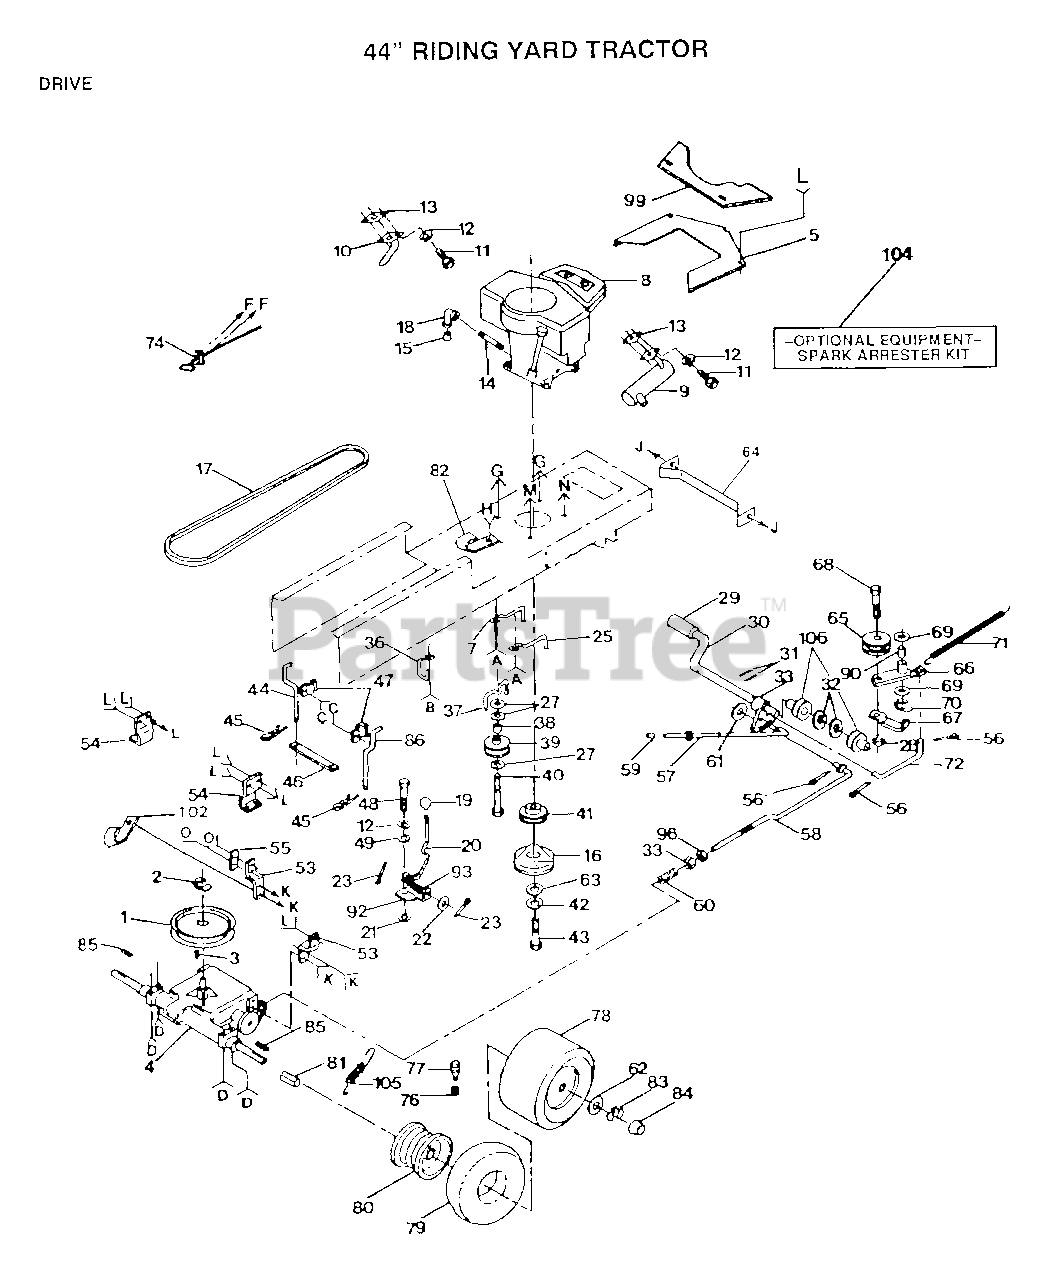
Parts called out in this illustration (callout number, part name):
1	PULLEY TRANSAXLE
2	RING
4	TRANSAXLE PEERLESS
5	SHIELD HEAT FRT
7	KEEPER BELT ENGLH
10	EXHAUST TUBE T
12	LOCKWASHER
14	PIPE NIPPLE
17	V BELT
18	STREET ELBOW LT
19	KNOB T (1/2-HOLE)
20	ROD SHIFTER T
21	WASH-SHFT PLT LT
22	WASHER
23	PIN COTTER 1/8
25	"KEEPER,BLT ENG LT"
27	WASHER
29	PEDAL COVER T
32	WASHER LT
33	NUT
37	BELT KEEPER LT
38	SPACER T
39	IDLER.FLAT.GTV
40	BOLT
42	LOCKWASHER
45	SPRING.RETAINER
46	STRAP LOCATOR
47	CLAMP LT
49	WASHER LT
53	STRAP TORQUE
54	BRACKET LT
55	PLATE-STRAP LT
56	COTTER PIN
57	ROD BRAKE PARK
58	ROD BRAKE
59	PLUNGER CAP T
60	SPRING ROD LT
61	WASHER
62	WASHER
63	WASHER
66	ARM IDLER
67	RETAIN BELT
69	WASHER LT
70	KLIP RING
71	"SPRING, RETURN LT"
72	"LINK, CLUTCH T"
76	VALVE CAP
77	VALVE STEM LT
78	TIRE REAR T
79	TUBE.18X9.5-8
81	SPACER HYT
82	BOLT
83	E RING HYT
84	HUB CAP
85	SQ KEY STD
90	"LY, BEARING"
92	PLATE SHIFT LT
93	SPRING LT
96	NUT
99	REAR BAFFLE T
102	CLIP T
106	NYLON BEARING
